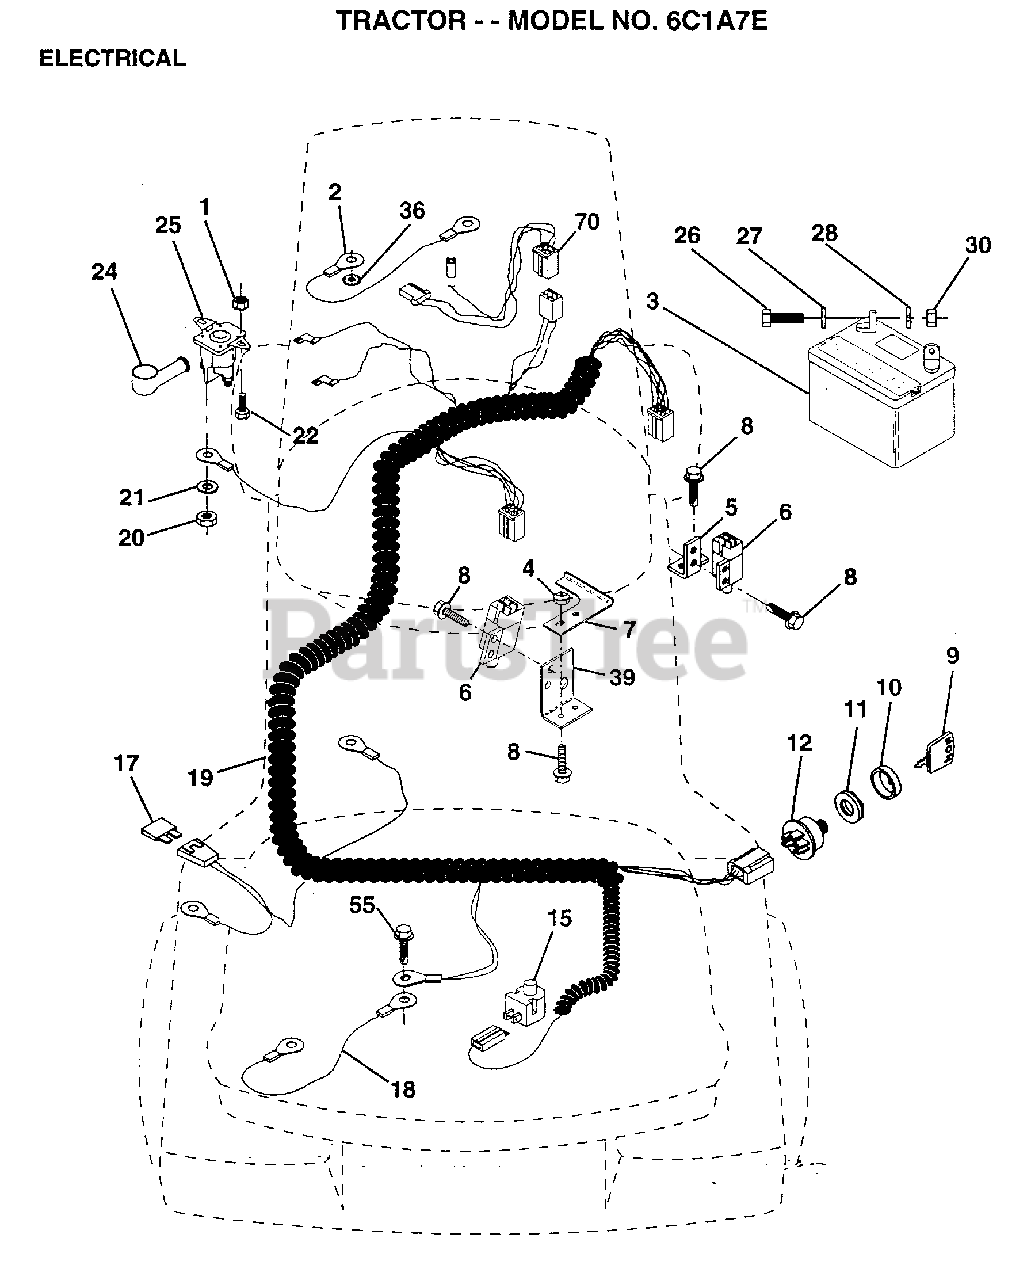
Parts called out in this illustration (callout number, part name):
1	NUT HXKEP 1/4X20
2	CABLE ASM.
4	LOCKNUT
5	BRACKET LT
6	SWITCH INTERLOCKT
7	KEEPER.ACTUAT.LR.
8	SCREW
9	KEY STEEL DELTA
10	COVER KEY SWITCH
15	SWITCH SEAT
17	FUSE HYT
18	CABLE ASSY
19	HARNESS.IGN.FEND.
20	NUT
22	BOLT HXHD FIN
26	BOLT LT
27	WASHER
28	LOCKWASHER
36	LOCKWASHER
39	BRACKET SWT CLUTC
55	SCREW LT
70	HARNESS ENG DUAL
